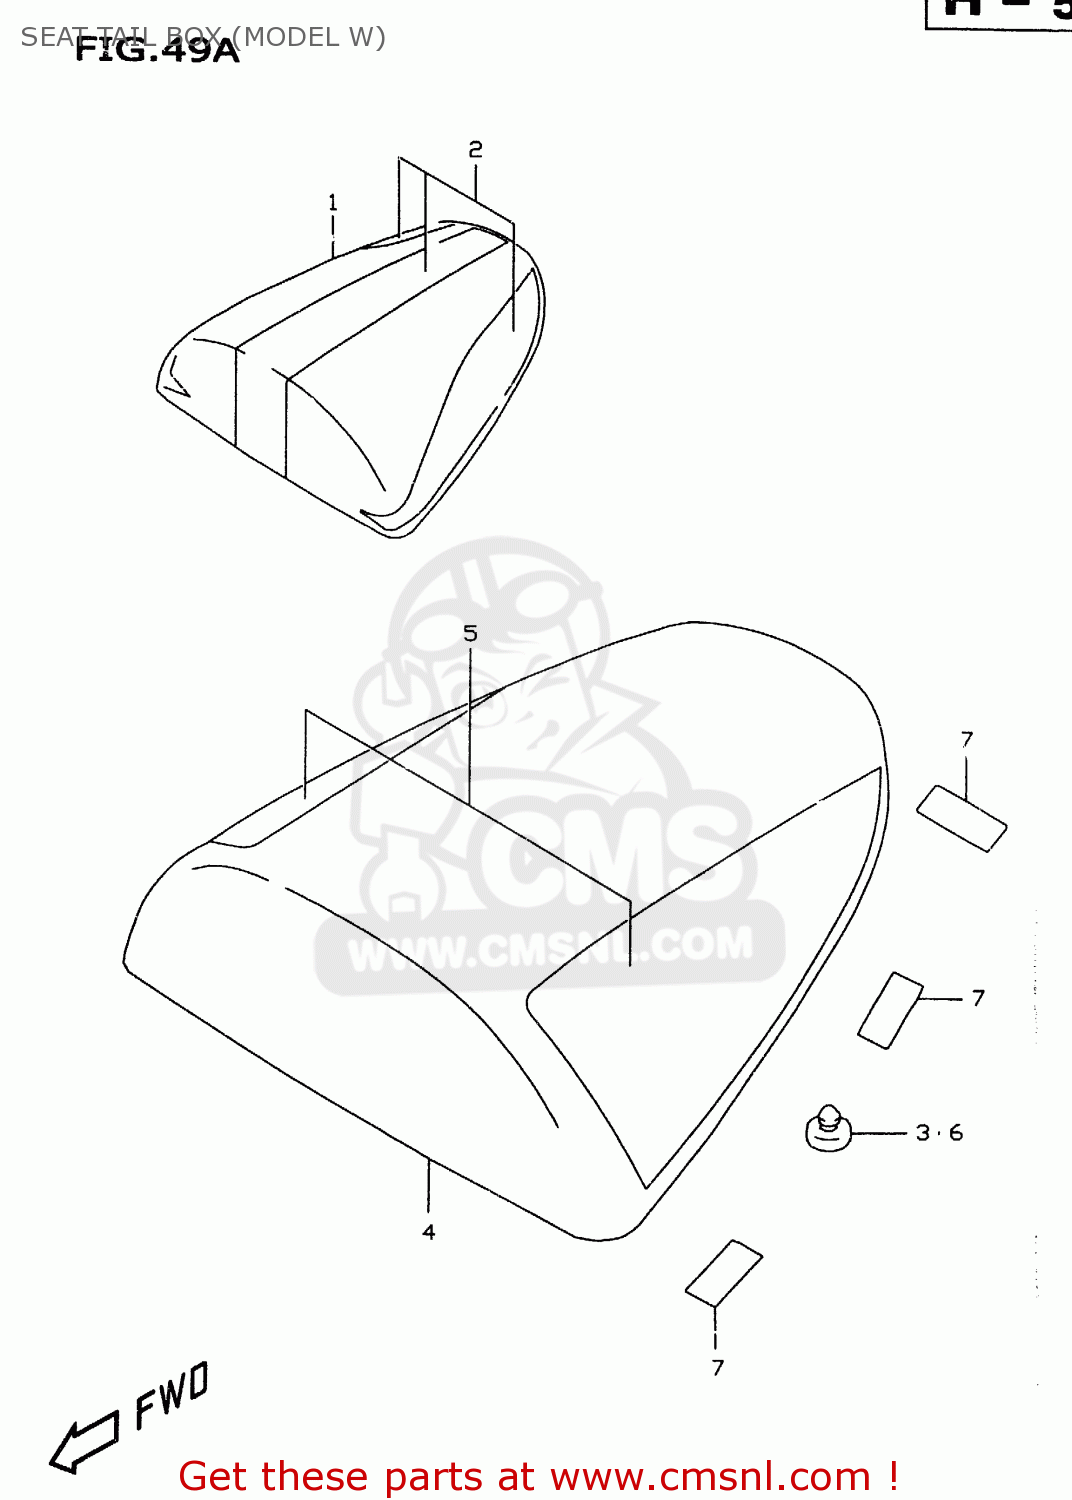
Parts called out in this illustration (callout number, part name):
1	BOX ASSY,SEAT TAIL(BLUE)
2	TAPE SET,BOX SEAT TAIL(WHITE)
3	CUSHION(11.5X22X20)
4	BOX ASSY,SEAT TAIL(BLACK)
5	TAPE SET,BOX SEAT TAIL
6	CUSHION(11.5X22X20)
7	PROTECTOR SET,SEAT TAIL BOX
